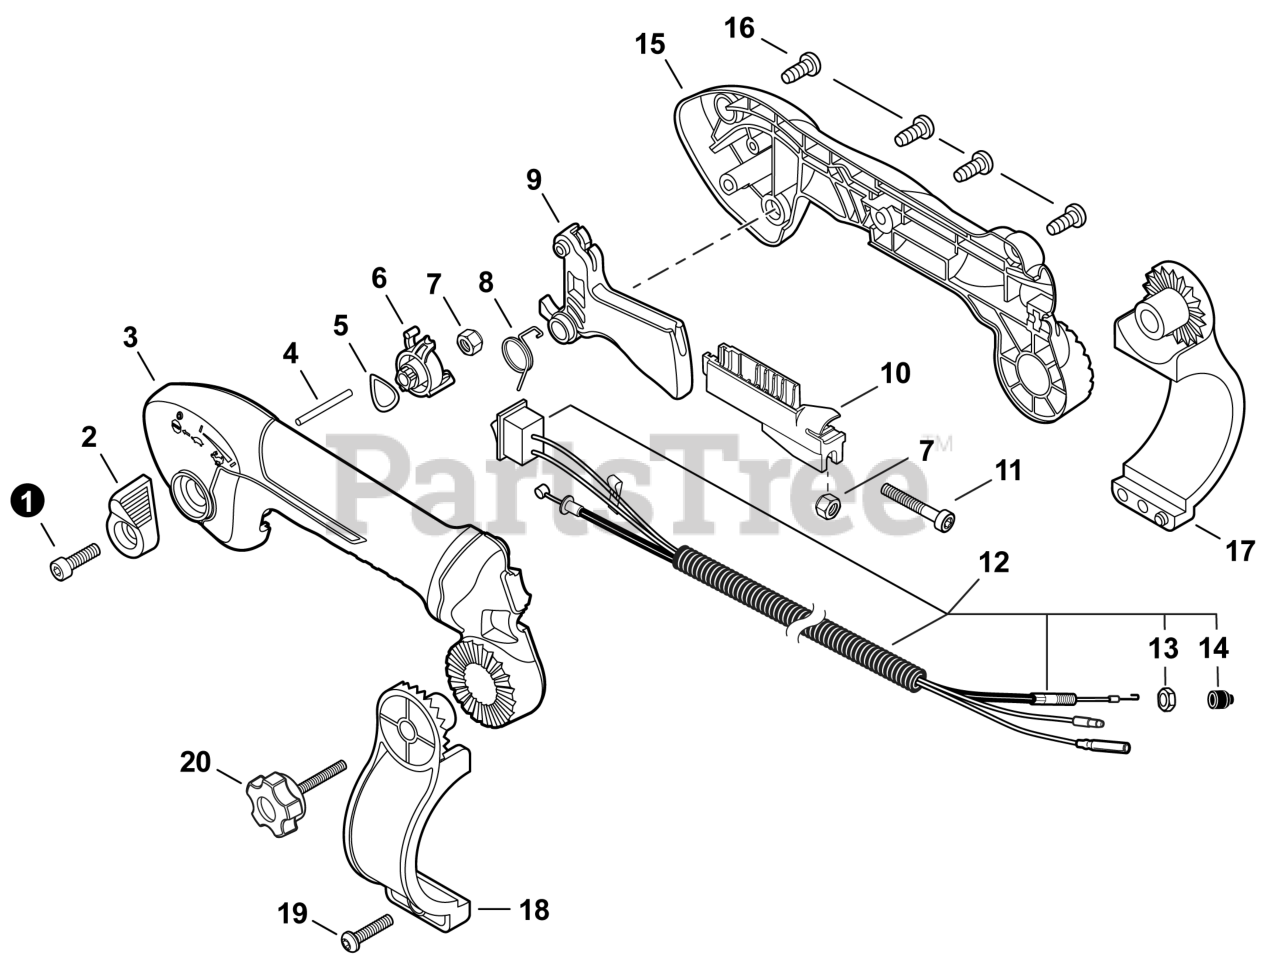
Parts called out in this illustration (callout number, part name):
1	BOLT, TORX 5x20
2	LEVER, THROTTLE
3	GRIP, HANDLE - LEFT
4	PIN 3x32
5	WASHER, WAVE 12
6	CONTROL, THROTTLE
7	NUT, LOCK M5
8	SPRING, TORSION
9	TRIGGER, THROTTLE
10	CONNECTOR, CABLE
11	BOLT, TORX 5x30
12	CABLE ASSY, CONTROL
13	NUT, HEX M6
14	CAP, DUST
15	GRIP, HANDLE - RIGHT
16	BOLT, TORX 5x16
17	BRACKET, HANDLE - RIGHT
18	BRACKET, HANDLE - LEFT
19	BOLT, TORX 5x20
20	KNOB, SCREW
